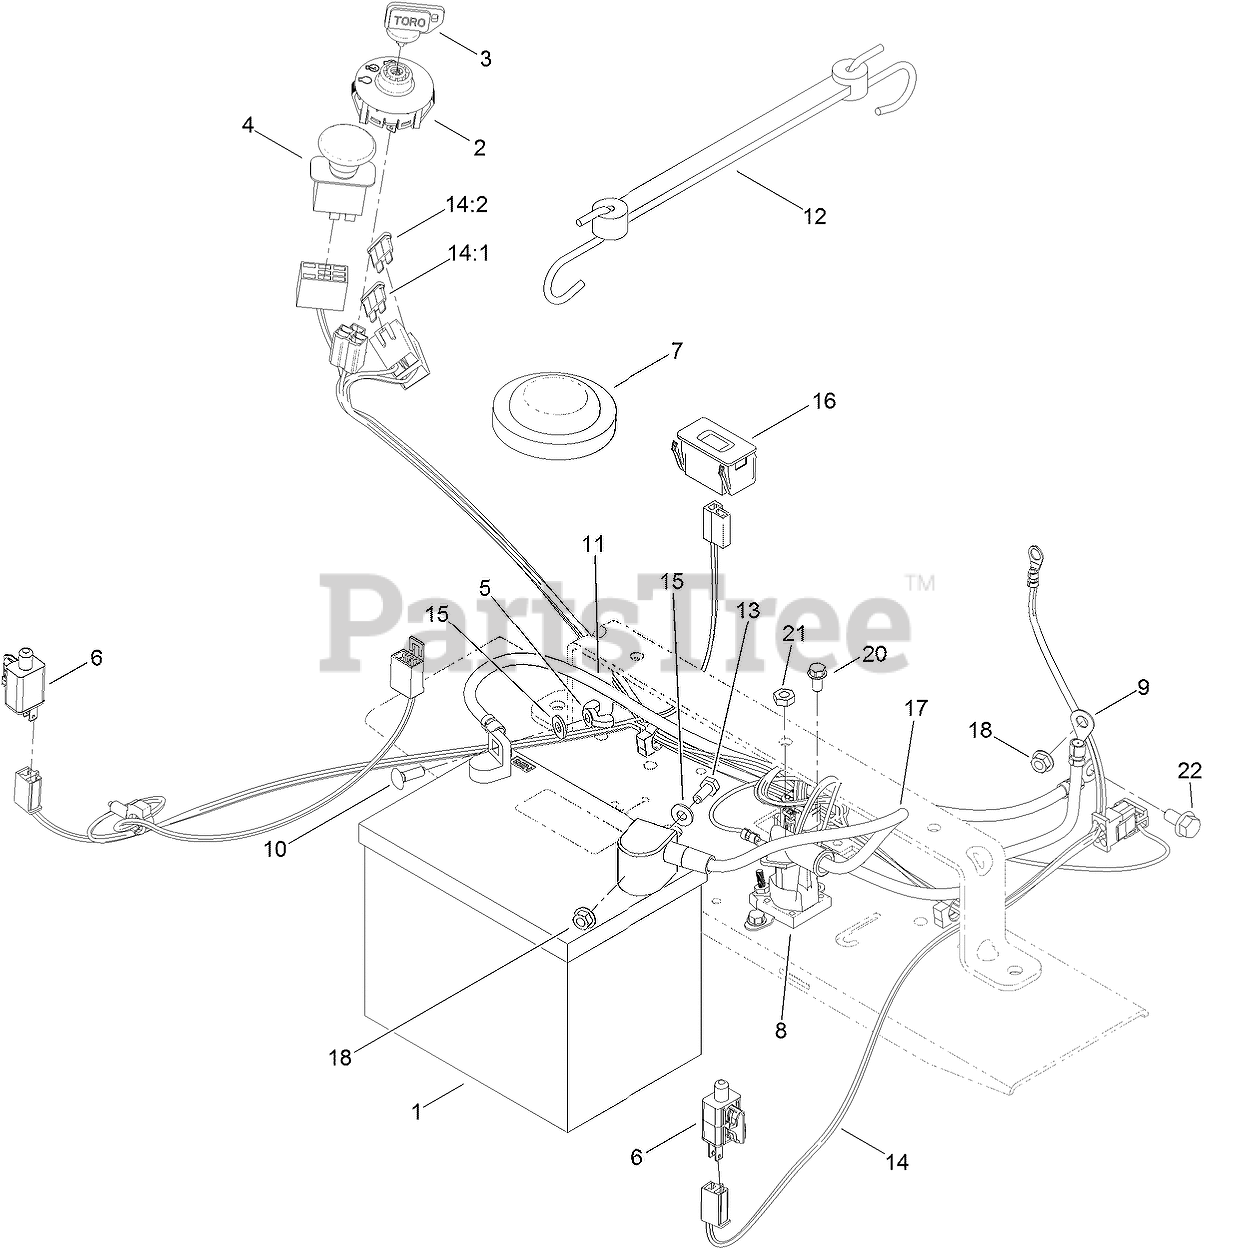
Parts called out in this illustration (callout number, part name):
1	BATTERY
2	SWITCH-IGNITION
3	KEY-IGNITION
4	SWITCH-PTO
5	NUT-WING
6	SWITCH
7	SWITCH-SEAT
8	SOLENOID
9	CABLE-BATTERY, RED
10	BOLT-CARR
11	CABLE-BATTERY, BLACK
12	HOLDDOWN-BATTERY
13	SCREW-HH
14	HARNESS-WIRE
14:1	FUSE-BLADE, 30 AMP
14:2	FUSE-BLADE, 25 AMP
15	WASHER-FLAT
16	HOURMETER
17	CABLE-BATTERY, RED
18	NUT-HF
20	SCREW-HWH
21	NUT-JAM
22	SCREW-HHF
